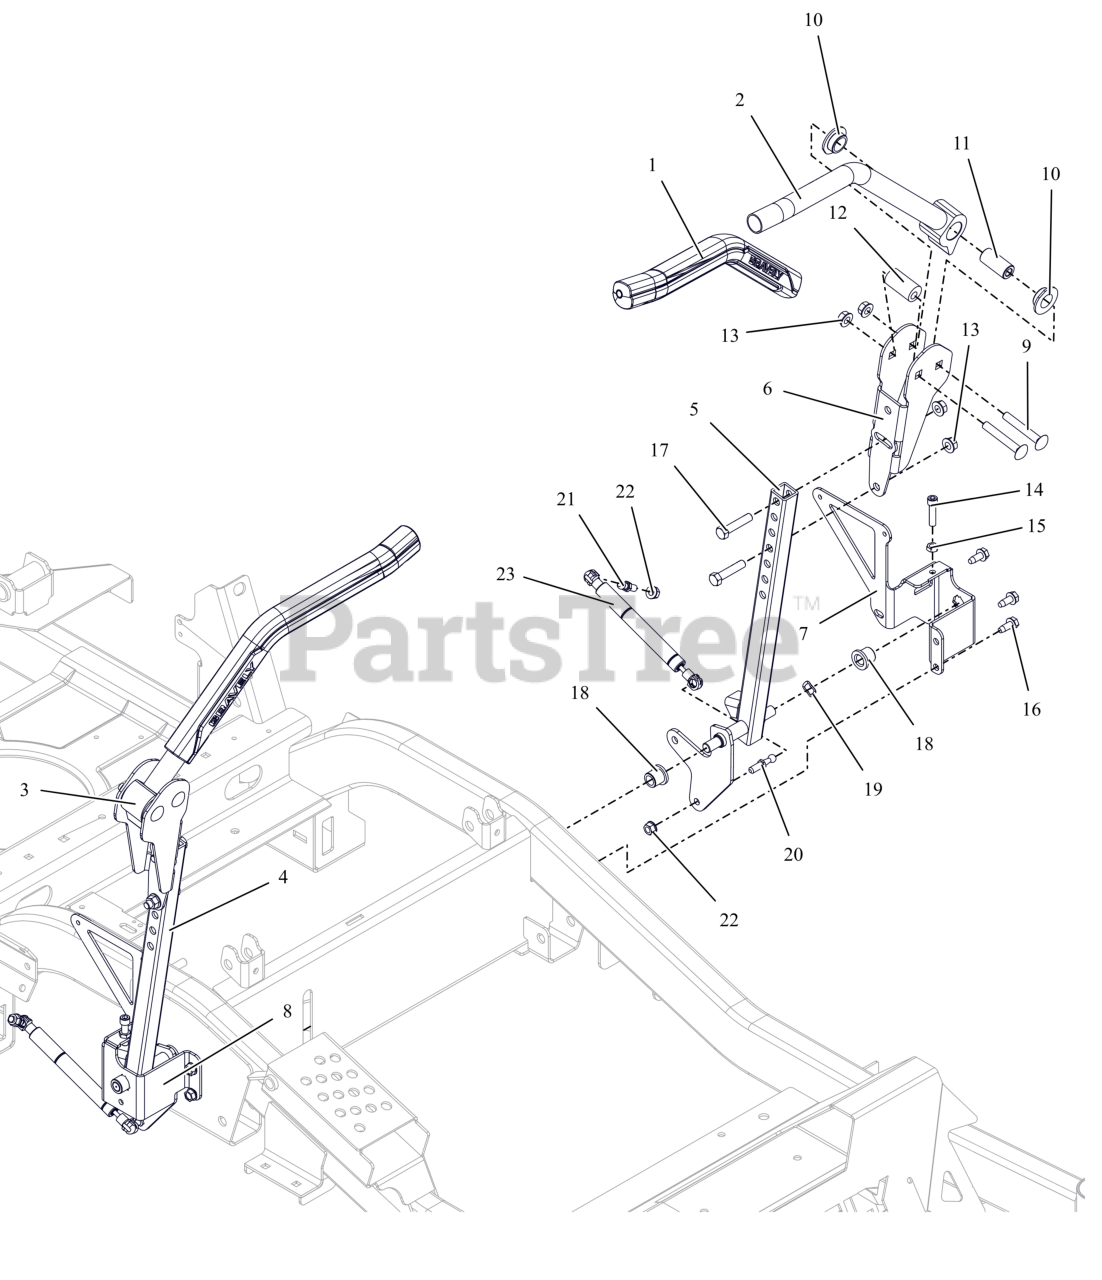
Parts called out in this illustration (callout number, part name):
1	GRIP- HANDLEBAR GRAVELY
2	WLDMT, CONTROL HANDLE-LH (BLACK)
3	WLDMT, CONTROL HANDLE-RH (BLACK)
4	WLDMT, STEERING RH (BLACK)
5	WLDMT, STEERING -LH (BLACK)
6	ADJ UPPER CONTROL ARM BRKT-BLK
7	BRKT, STEERING ARM MOUNTING -LH (MATTE BLACK)
8	BRKT, STEERING ARM MOUNTING- RH (MATTE BLACK)
9	BLT, RHSSN.38-16X2.50 G5 ZCC
10	BSHG, FLANGED .762 X 1.48 X .44 IGLIDER
11	SPACER, STEERING ARM
12	BSHG, ECCENTRIC.406X.875X1.625
13	NUT-LK-TOP-FLG .38-16 ZC120
14	SCR, SKH .312-18X1.25 GR8 ZC120
15	NUT-JAM .312-18 G2 ZCC
16	SCR,TAP .312-18X.75 HWH TR ZCC
17	BLT, HEX .38-16X1.75 G5 ZCC
18	BHSG-FLG .500X.750X.750X.125
19	WAVE WASHER .531X.781X.125FH
20	STUD-BALL-THREADED
21	STUD- BALL
22	NUT,LK-CTR-FLG .31-18 GF ZCC
